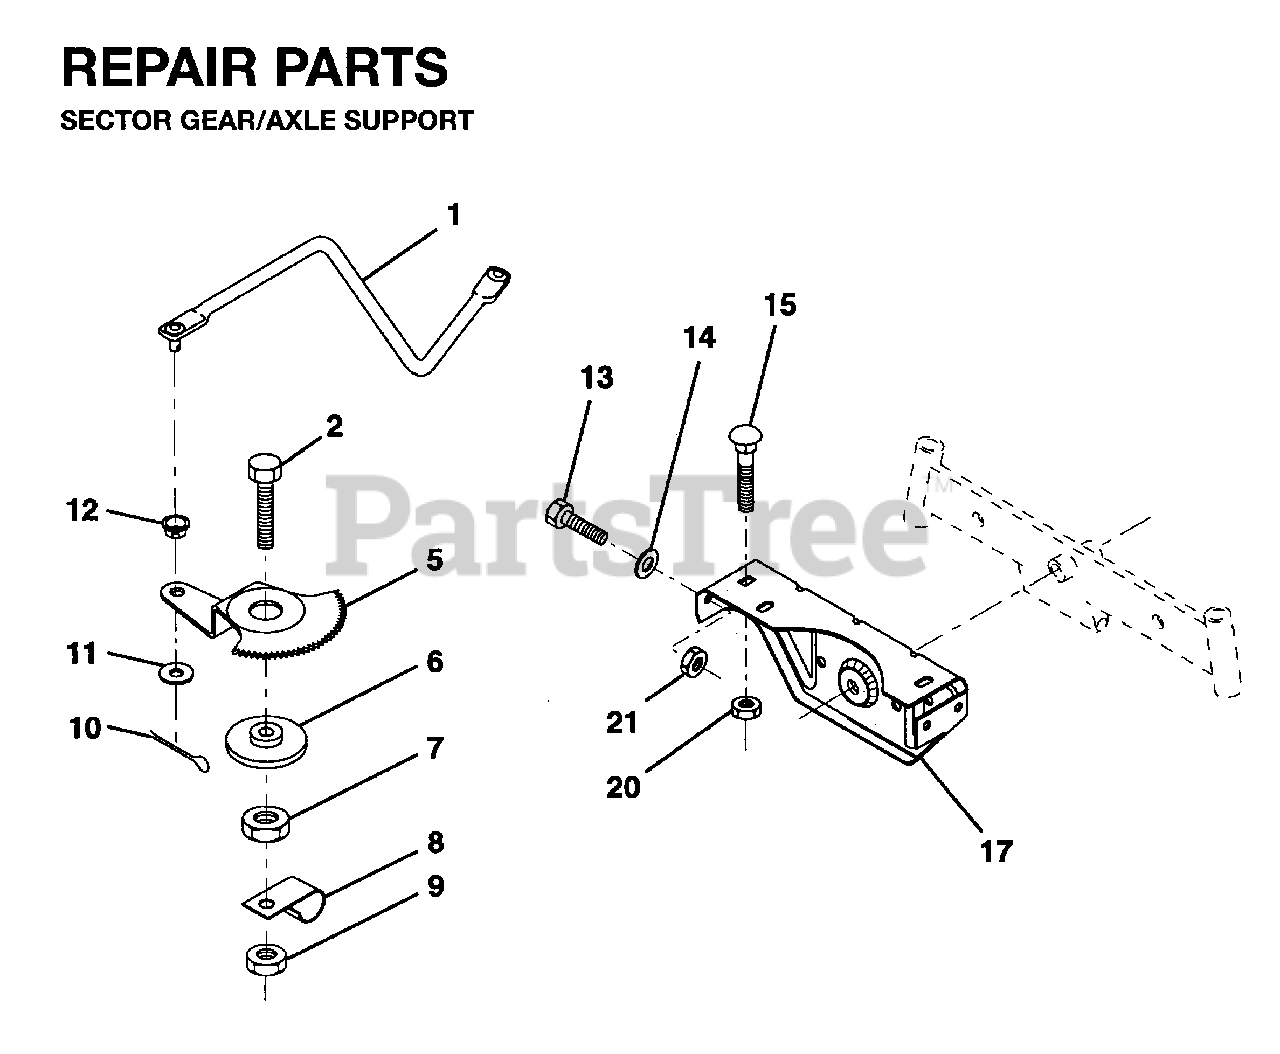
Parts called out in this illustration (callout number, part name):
1	LINK DRAG
5	GEAR SECTOR
7	NUT LTV
8	CLIP INSULATOR
9	NUT LTV
10	COTTER PIN
11	WASHER
12	BUSHING.DRAGLINK
13	BOLT
14	WASHER - 25X8.5X2.3
17	SUPPORT/AXLE FRONT
20	LOCKNUT
21	NUT.71038.31-18.HEX.NYLOCK
